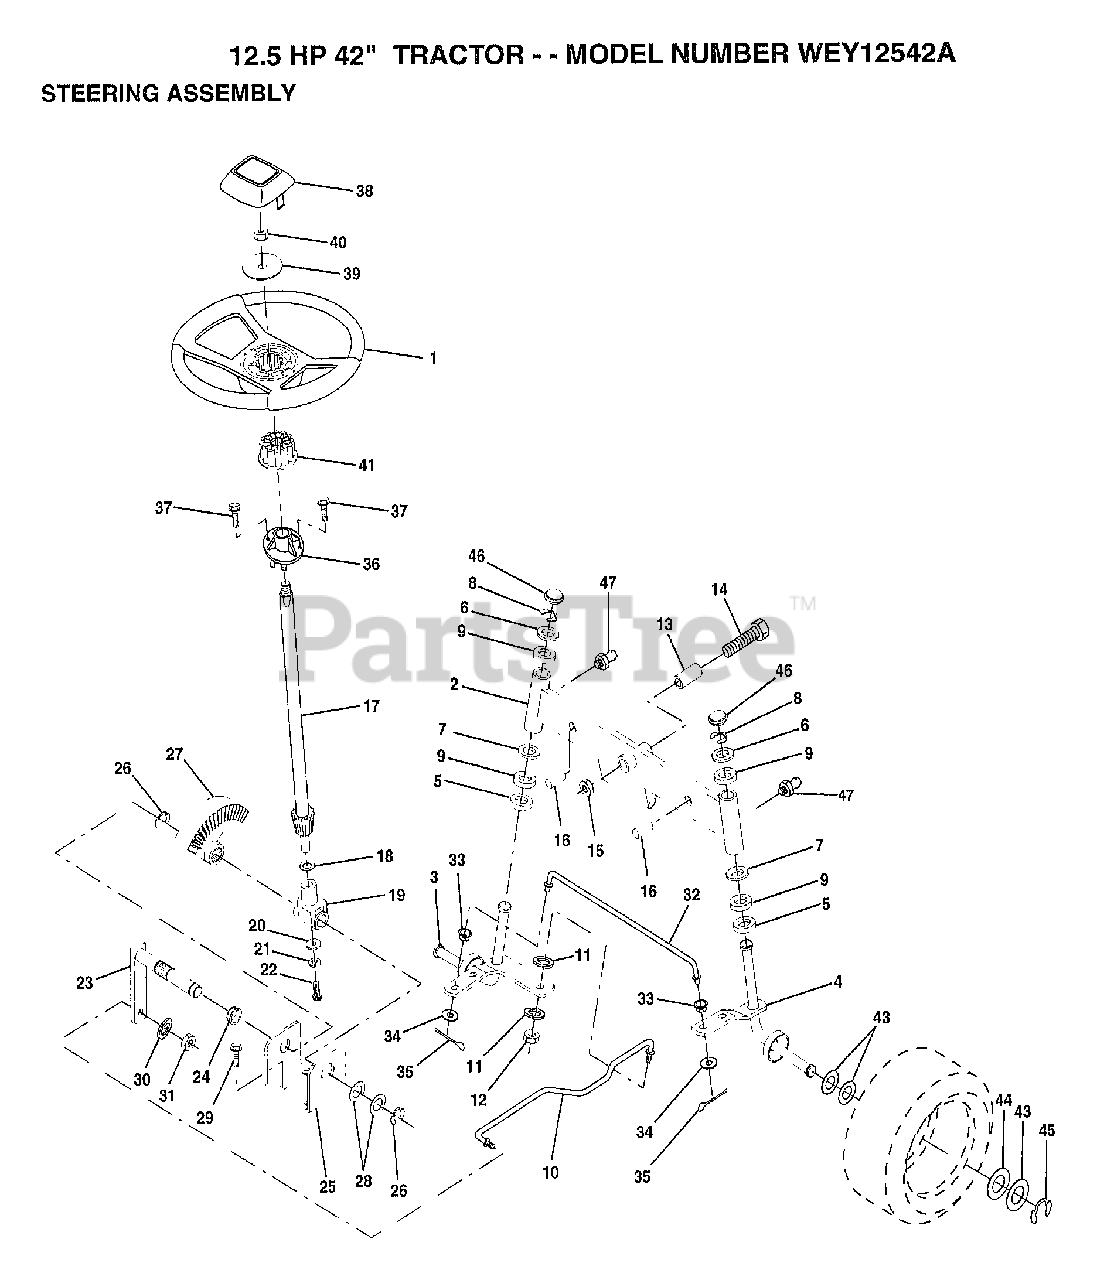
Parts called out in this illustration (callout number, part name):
3	SPINDLE LH
4	SPINDLE RH
5	WASHER .T
6	WASHER
7	WASHER
8	RING
9	COL. SRTG. BEAR.
11	LOCKWASHER
13	BEARING
14	BOLT HEX 5/8-11
15	"NUT-LOC,FLANGE LT"
16	AXLE PIN
17	STEERING SHAFT
18	THRUST WASHER
19	SUPPORT.SHAFT
21	LOCKWASHER
22	"SCREW,SPECIAL"
24	NYLINER T
25	"BRKT,STEERING"
26	RING
27	GEAR SECTOR
28	WASHER .T
29	SCREW
30	LOCKWASHER
32	TIE ROD
33	BUSHING.DRAGLINK
34	WASHER
35	COTTER PIN
38	ST WHL INSERT CAP
39	WASHER
41	ADAPTER LT
43	WASHER
44	WASHER
45	RING
46	CAP
47	ZERK M
